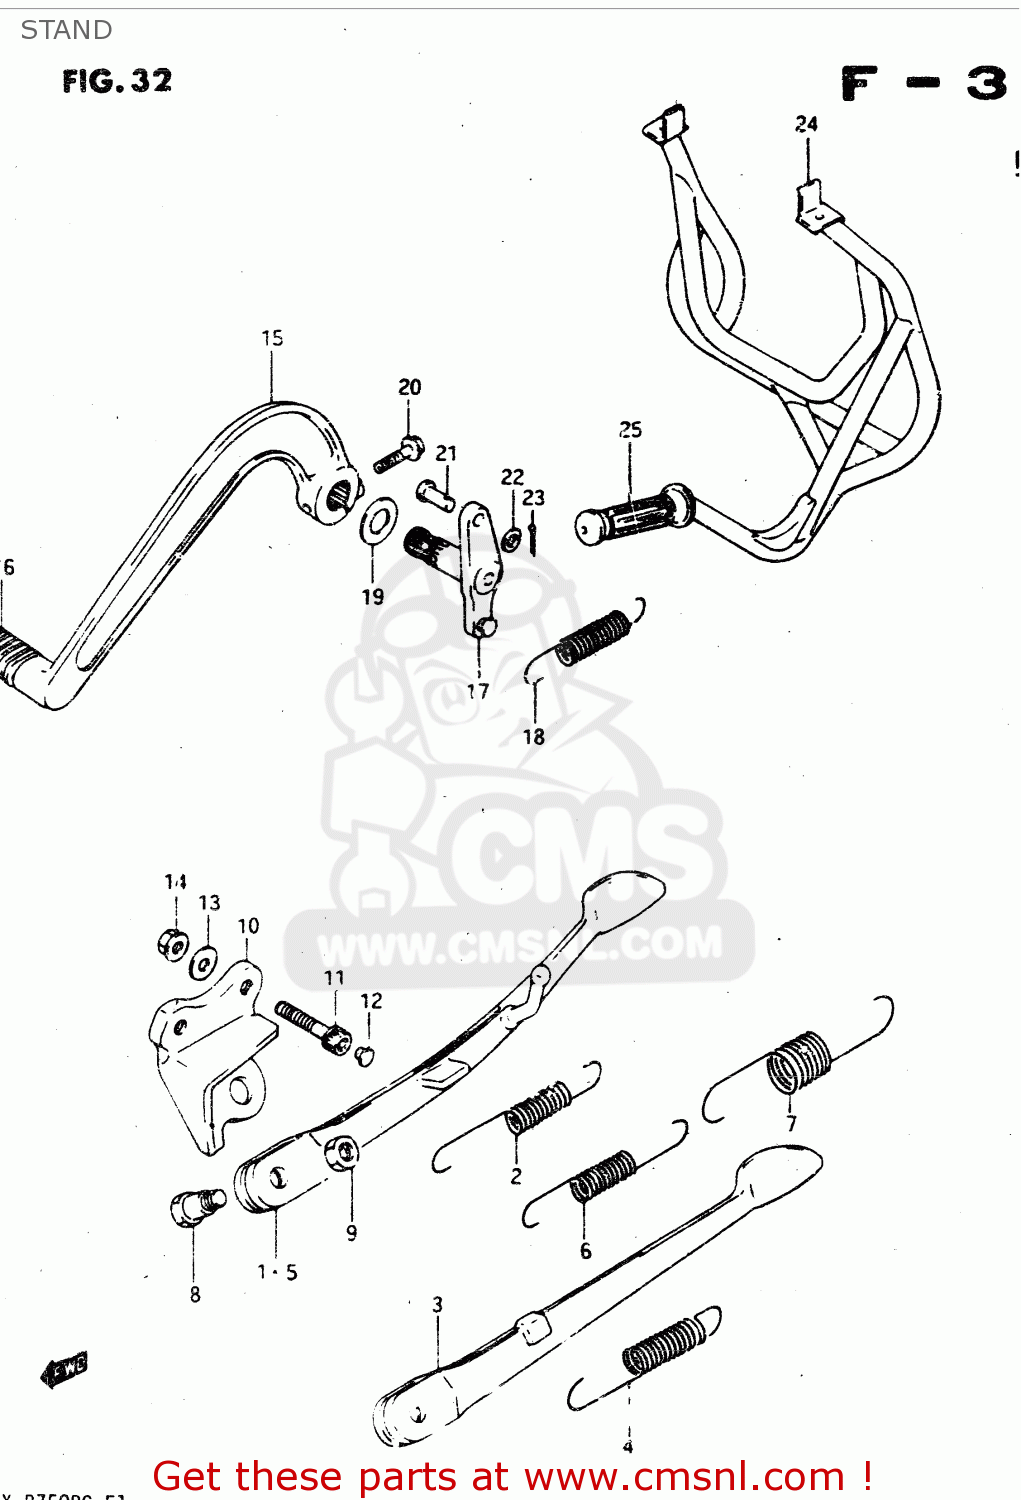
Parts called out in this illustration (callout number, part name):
1	STAND,SIDE
2	SPRING
3	STAND, PROP (SILVER)
4	SPRING
5	STAND, PROP (SILVER)
6	SPRING
7	SPRING
8	BOLT(10X38)
9	NUT
10	BRACKET,SIDE STAND
11	BOLT
12	CAP,ENGINE MOUNTING
13	WASHER
14	NUT
15	PEDAL,BRAKE
16	RUBBER,BRAKE PEDAL
17	ARM COMP,BRAKE ROD
18	SPRING
19	WASHER,BRAKE PEDAL
20	BOLT (6X20)
21	PIN
22	WASHER
23	PIN
24	STAND,CENTER
25	GRIP,L
